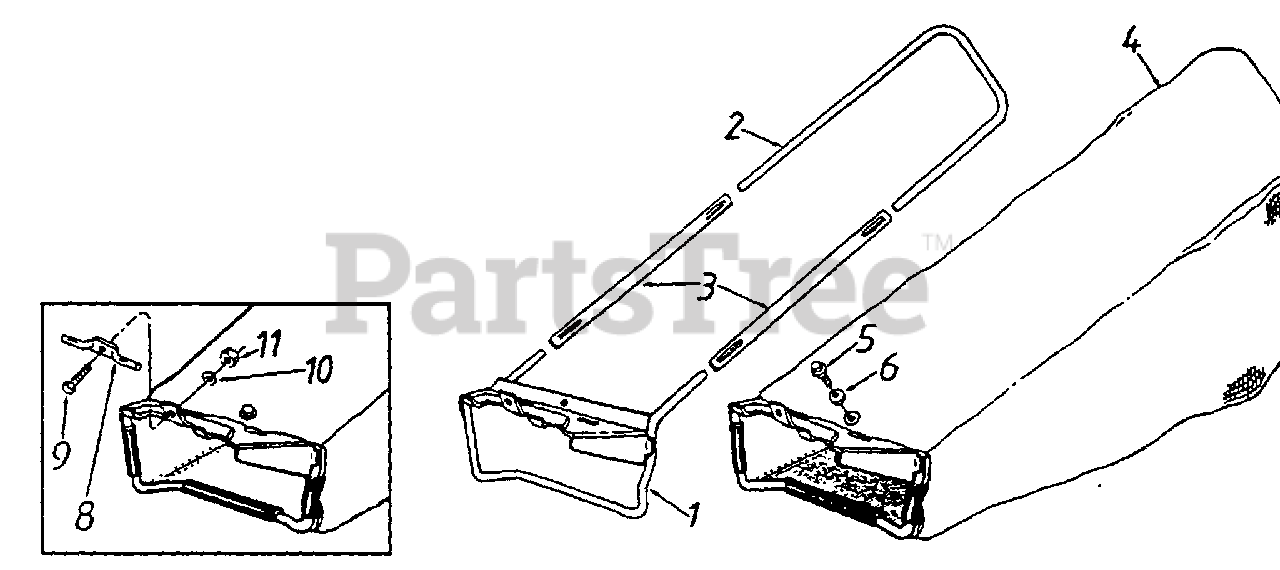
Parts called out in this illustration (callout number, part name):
4	Grass Bag
5	Hex Wash. Hd. TT-Tap Scr. 1/4-20 x 5" Lg.
6	Bell-Wash. 1/4" I.D.
8	Grass Bag Hook
9	Hex Bolt 1/4-20 x .62" Lg.
10	L-Wash. 1/4" I.O.
11	Hex Nut 1/4-20 Thd.
